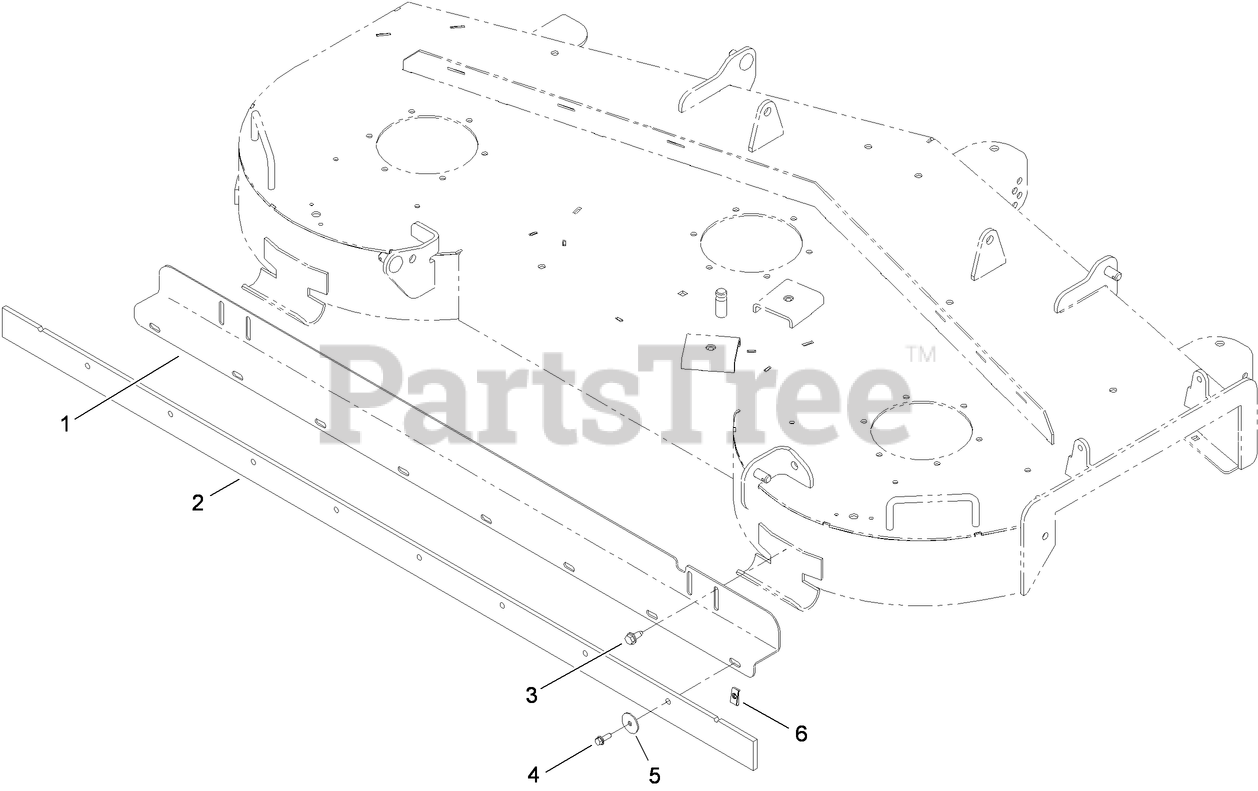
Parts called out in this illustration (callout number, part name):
3	SCREW-HWHTF
4	SCREW-HHF
5	WASHER-FLAT
6	NUT-SPEED
